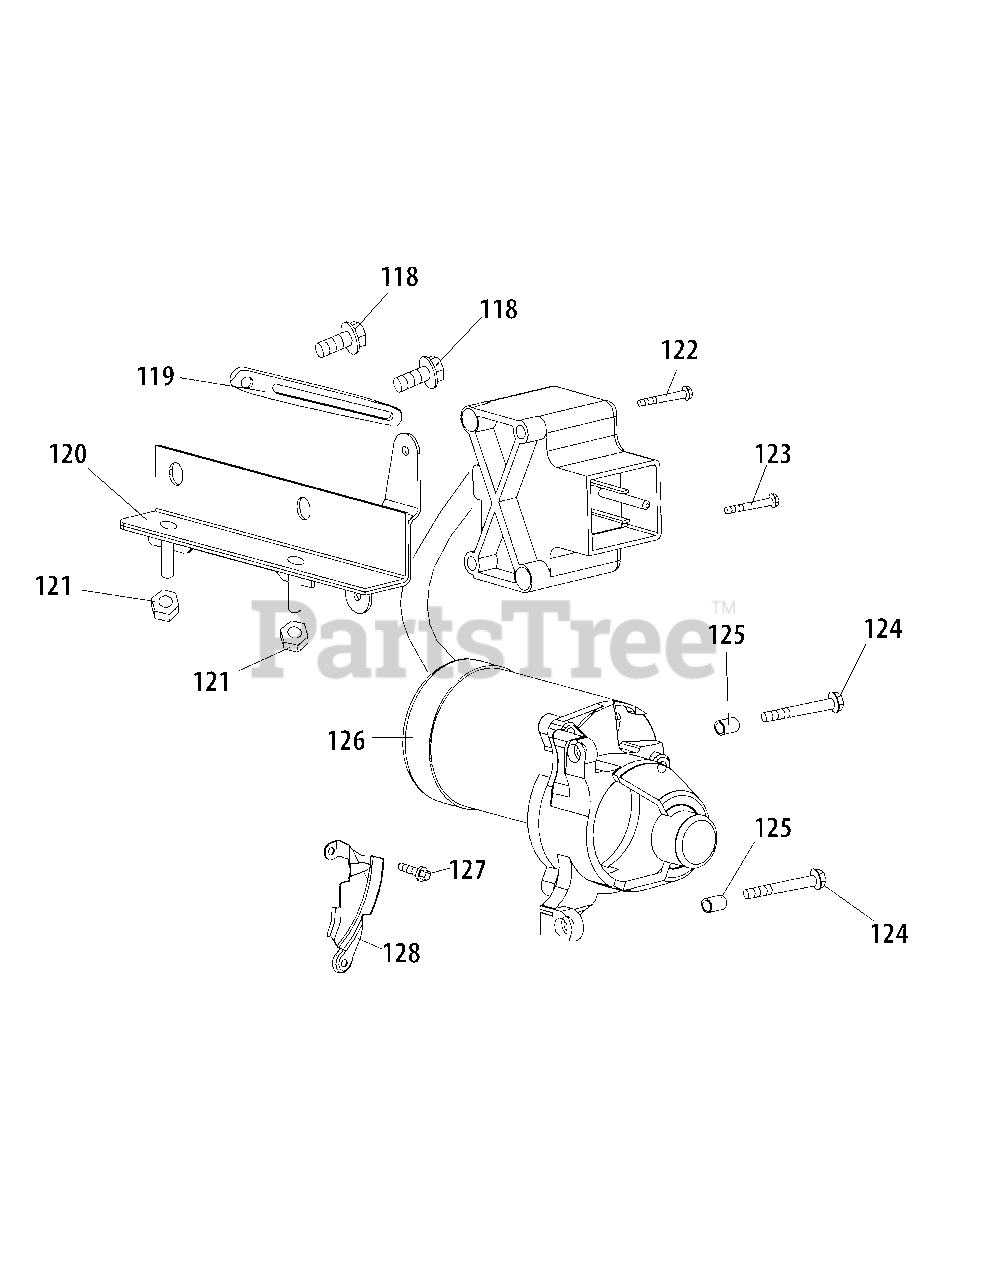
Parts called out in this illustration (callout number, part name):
118	Bolt - Flange M6
119	Flexible Clamp
120	Bracket - Switch Housing Mount
122	Screw M4 X 55
123	Screw - M4 X 60
124	Bolt-M6 X 32
125	Pin - Dowel
126	Electric Starter
127	Bolt - M6 X 12 Zin
128	Shield - Blower Housing
